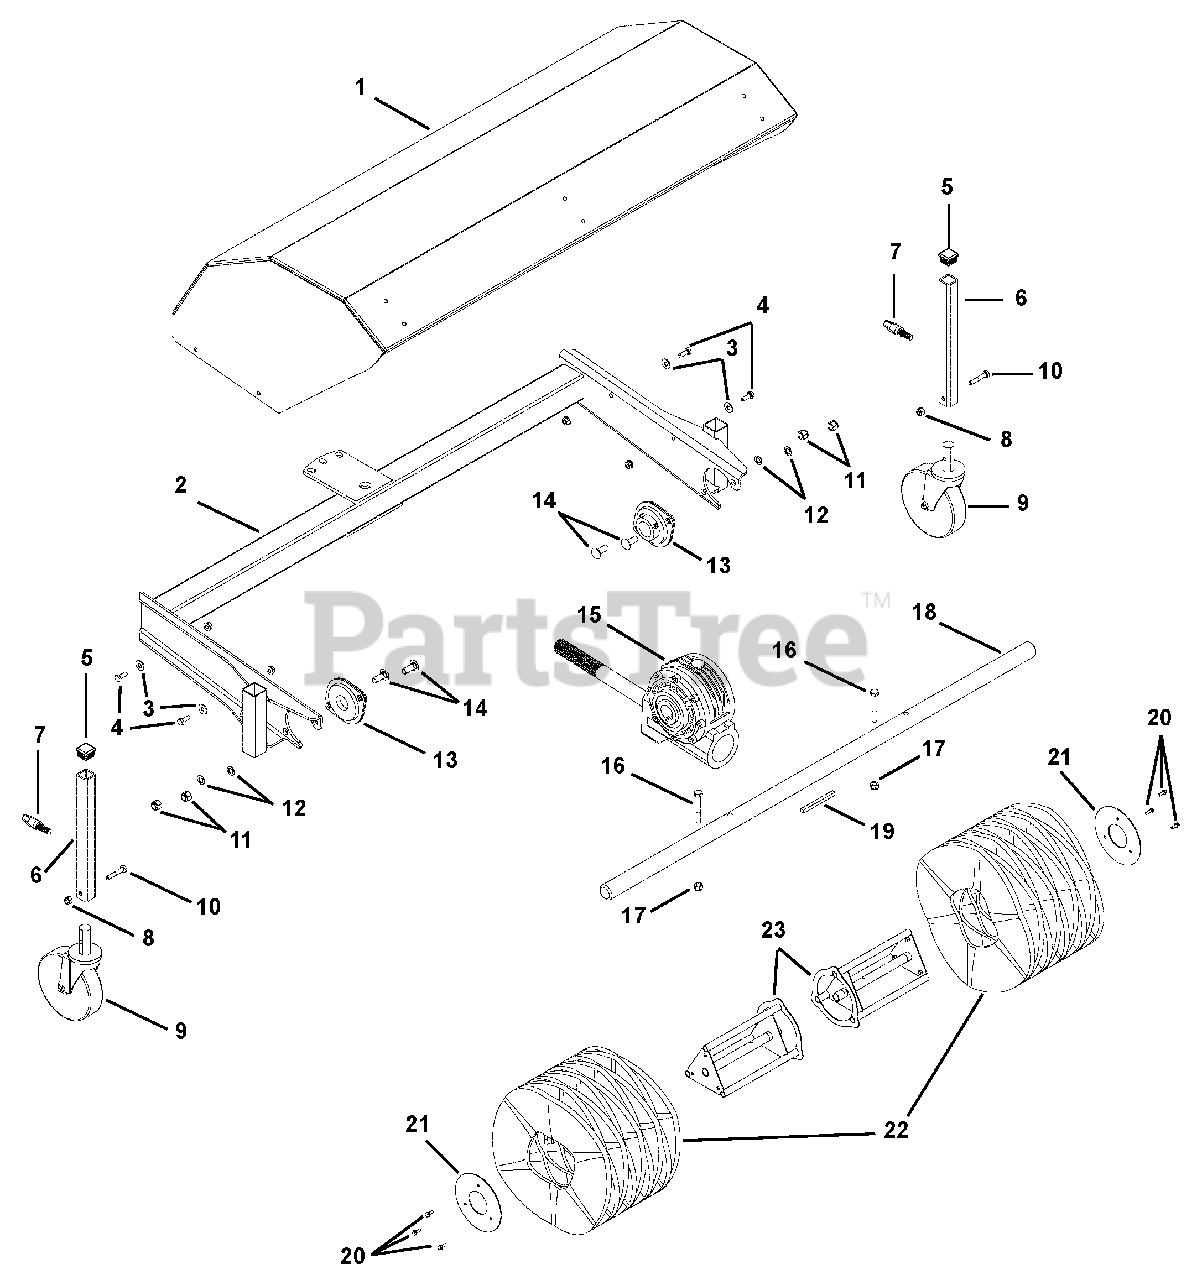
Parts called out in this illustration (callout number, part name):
1	HOOD, 36" BRUSH - W/DECALS
2	FRAME, BRUSH-W.U. 3' BRUSH
3	@WSHR-FL-STL.312X.734X.065 YWZ
4	@BLT-HEX .25-20X.75 GR5 YWZC
5	PLUG, SQUARE-1" PLASTIC
6	LEG, CASTER WHEEL
7	KNOB, BLACK
8	@NUT-LK-NYL .250-20 YWZC
9	CASTER WHEEL,5"X1.250" 7/8 STE
10	@BLT-HEX .25-20X1.50 GR5 YWZC
11	@NUT-LK-NYL .38-16 YWZC
12	WASHER, SAE 3/8
13	BEARING, 1 1/8" FLANGETTE
14	@BLT-RDHDSQNK .38-16X1.00 G5YZ
15	GEARBOX, WORM ALUMINUM-8.25:1
16	@BLT-HEX .31-18X2.25 GR5 YWZC
17	@NUT-LK-NYL .312-18 YWZC
18	SHAFT, THRU 1-1/8 X 3' MCD
19	KEY, SQUARE .25X.25X3 LG
20	HHCS, SERRATED FLANGE 3/8-16X1
21	PLATE, END RETAINER
22	KIT, BRISTLE - SET OF 18
23	CORE, WELDMENT 3' MCD
